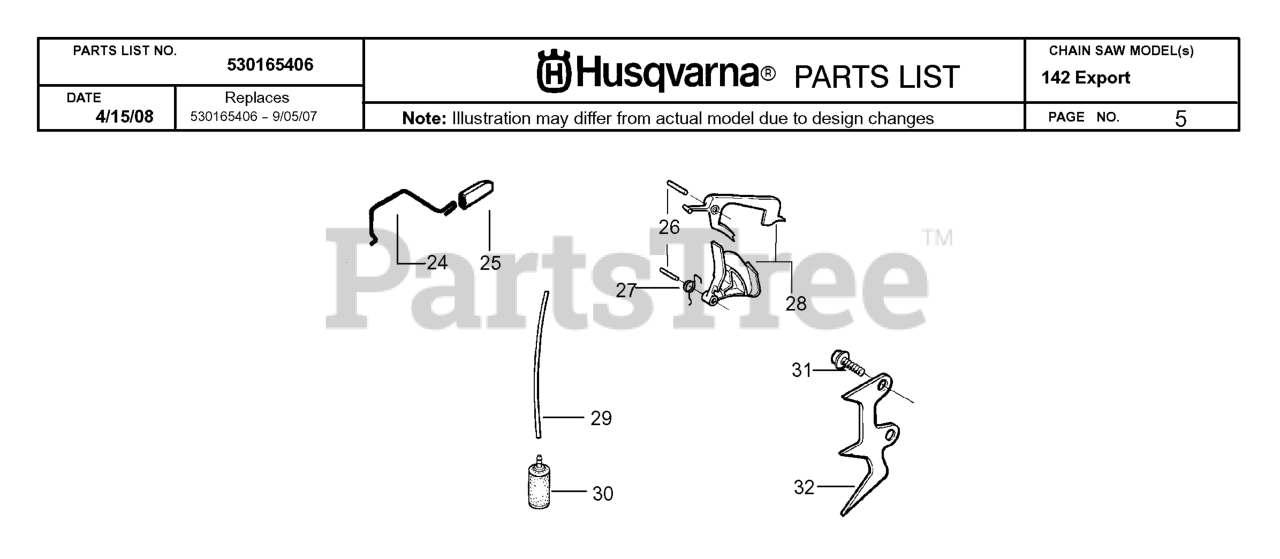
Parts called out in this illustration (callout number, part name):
24	THROTTLE SHAFT 36/41
25	THROTTLE ACTUATOR 36/41
26	PIN,TRIGGER 36/41
27	TRIGGER SPRING 36/41
28	THROTTLE TRIGGER-KIT
29	HOSE. FUEL
30	FUEL PICK-UP
32	SPIKE 36/41
